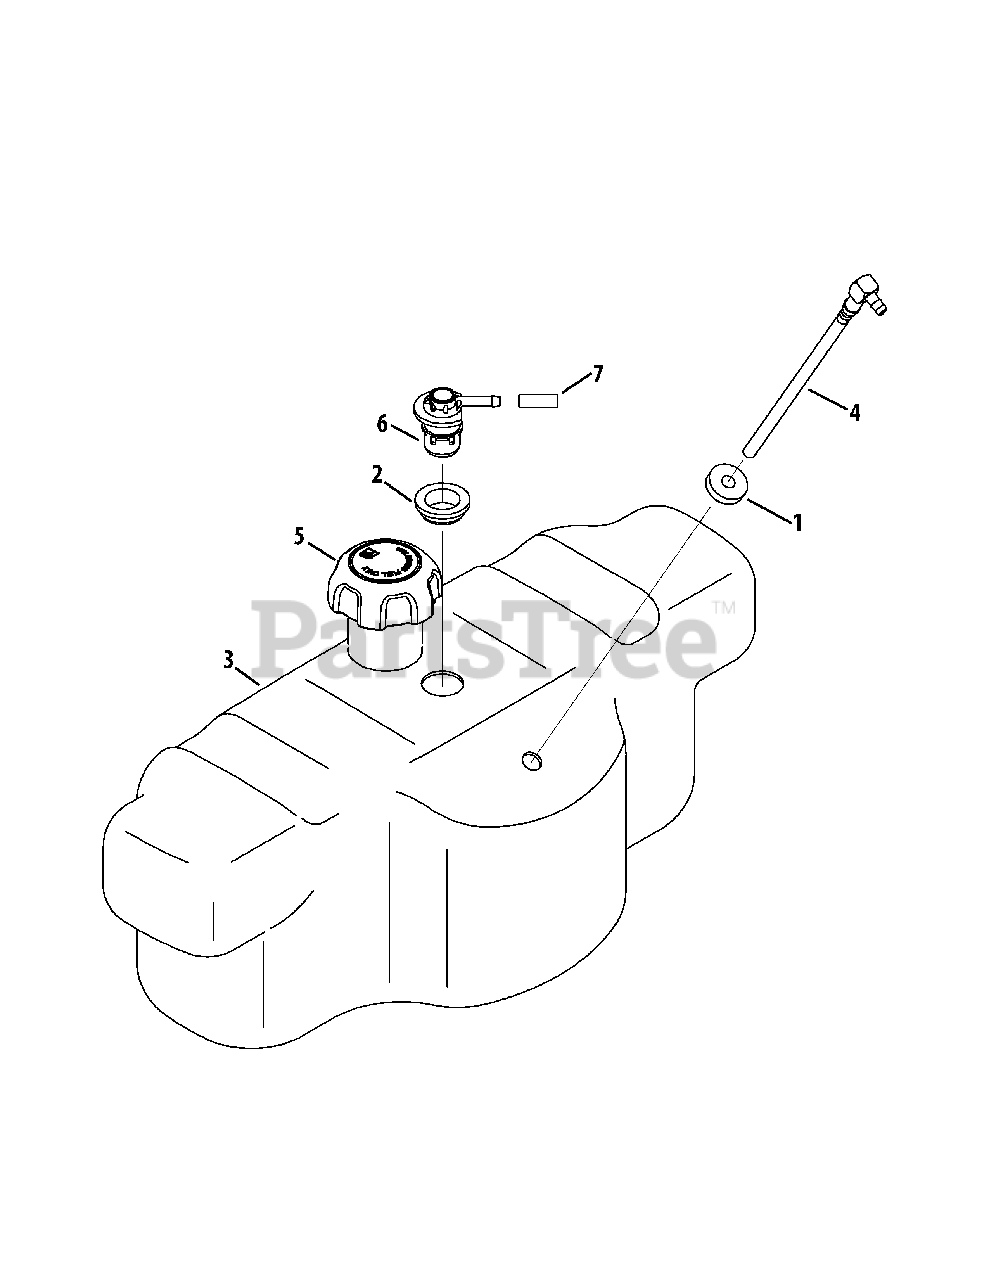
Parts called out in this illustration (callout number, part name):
1	Fuel Tank Bushing
2	Rubber Grommet
3	Fuel Tank
4	Fuel Pick-Up Fitting
5	Fuel Cap
6	Fuel Rollover Valve
7	Vent Hose
